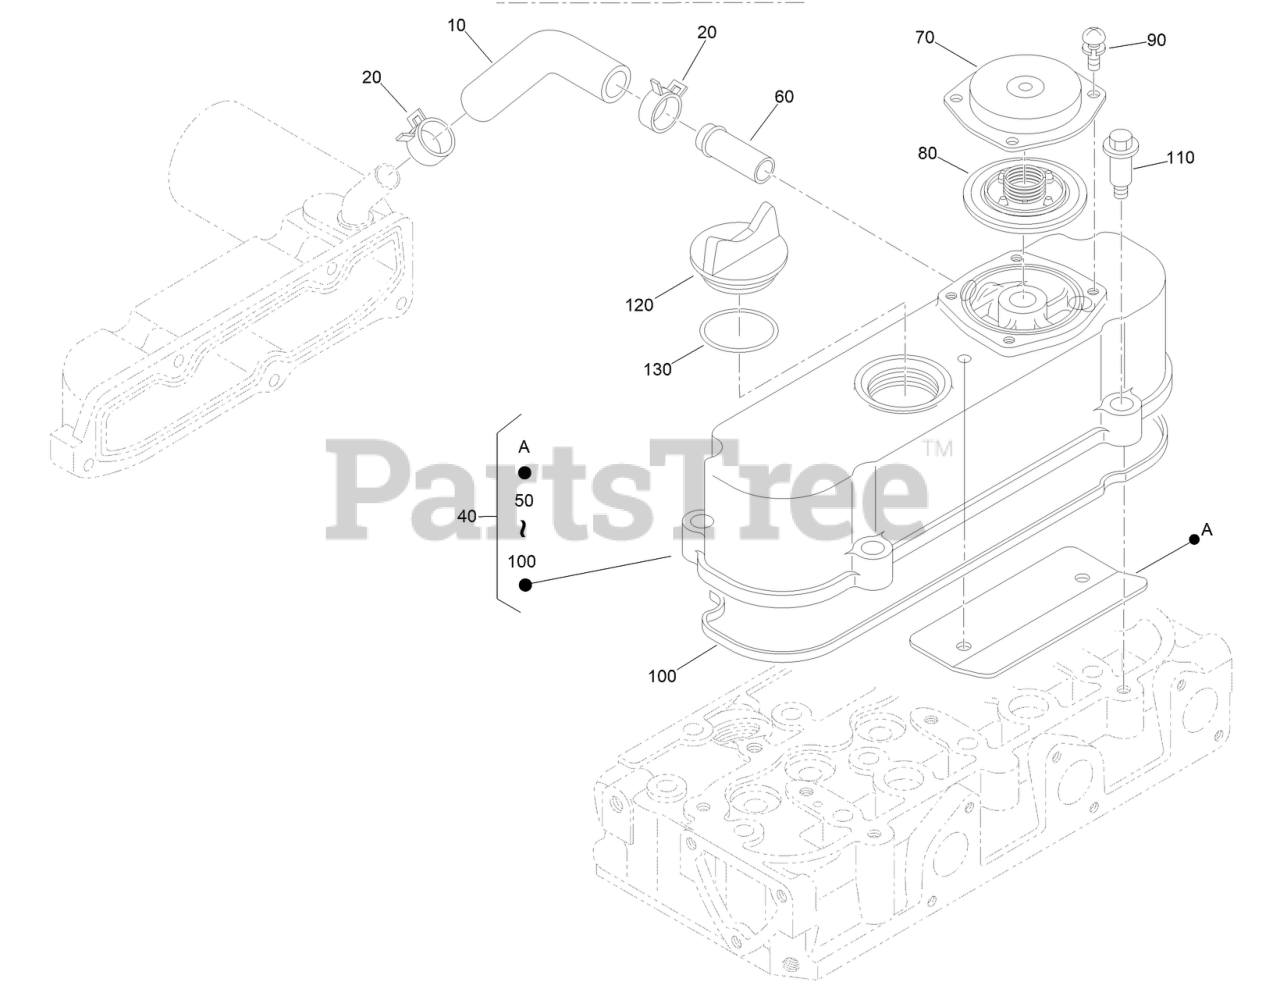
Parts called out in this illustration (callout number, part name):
10	TUBE (BREATHER)
20	CLAMP-HOSE
40	COVER-CYLINDER HEAD
50	CYLINDER HEAD ASM
60	PIPE-RETURN, WATER
70	COVER-BREATHER
80	VALVE-BREATHER
90	SCREW (WITH WASHER)
100	GASKET-COVER, HEAD
120	PLUG-FILLER, OIL
130	O RING
